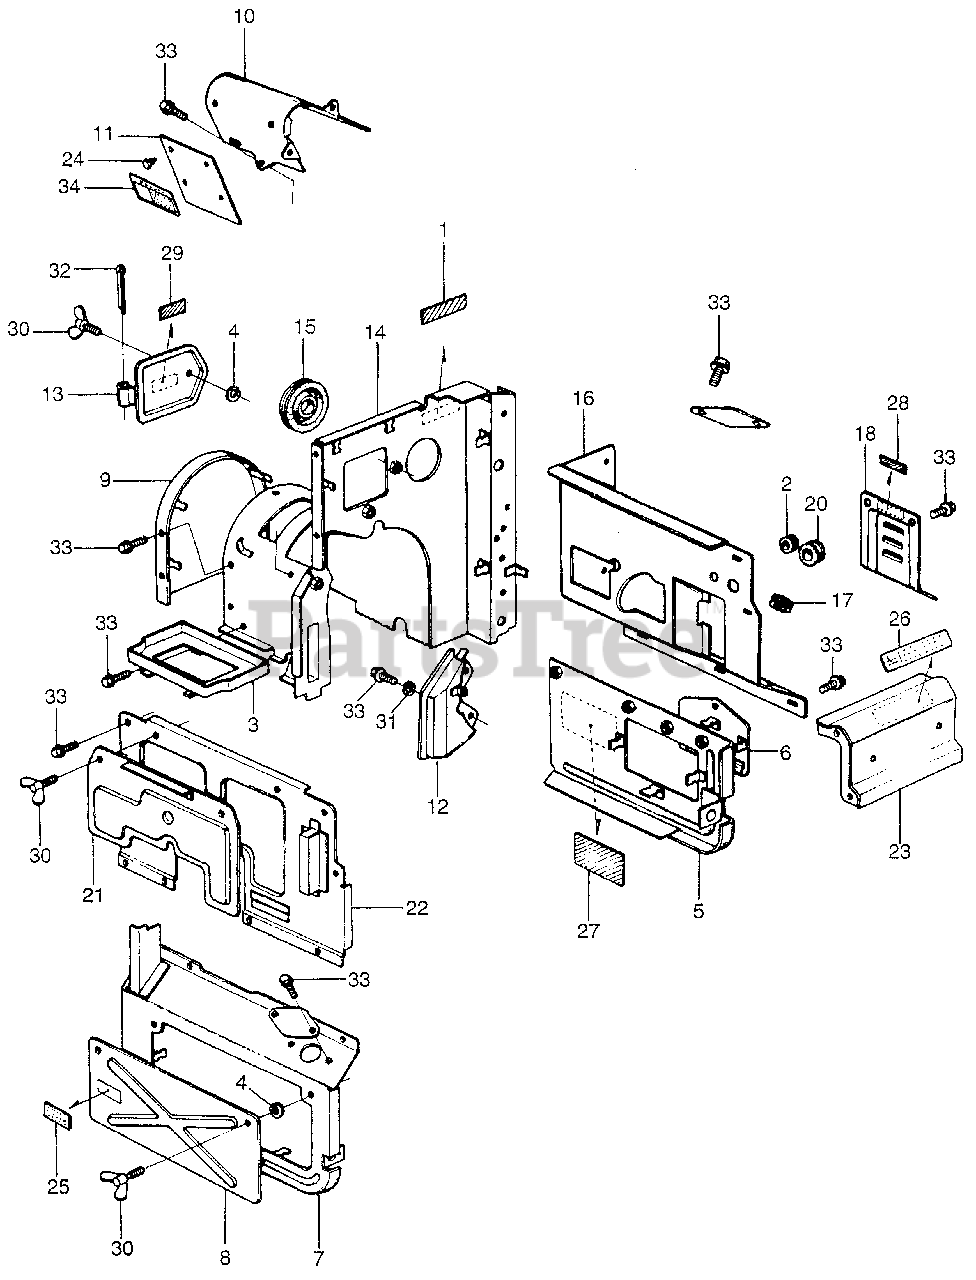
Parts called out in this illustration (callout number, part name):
1	MARK, RADIATOR CAUTION
2	RUBBER, REGULATOR CUSHION
3	CASE, BATTERY
4	STOPPER, TOOL BOX LATCH
5	COVER, R. SIDE
6	COVER, R. SIDE SUB
7	COVER, L. SIDE
8	COVER, L. SIDE SUB
9	COVER, ALTERNATOR END
10	COVER, STARTER MOTOR (NOT AVAILABLE)
11	RUBBER, STARTER MOTOR COVER
12	COVER, ALTERNATOR DUCT
13	COVER, POINT
15	GROMMET, WATER HOSE
16	SEPARATOR, CARBURETOR
17	GROMMET, CARBURETOR SEPARATOR
18	COVER, GOVERNOR
20	GROMMET, BOOST TUBE
21	COVER, PLUG
22	SUPPORT, PLUG COVER
23	PLATE, JOINT
24	PIN, RUBBER SET
25	MARK, TIMING
26	MARK, OIL LEVEL
27	MARK, BELT ADJUSTMENT
28	MARK, GOVERNOR OIL
29	MARK, CONTACT
30	BOLT, WING
31	WASHER, SPRING (6MM)
32	PIN, COTTER (3.0X45)
33	BOLT, FLANGE (6X12)
NI	MARK, HOT AIR VALVE
